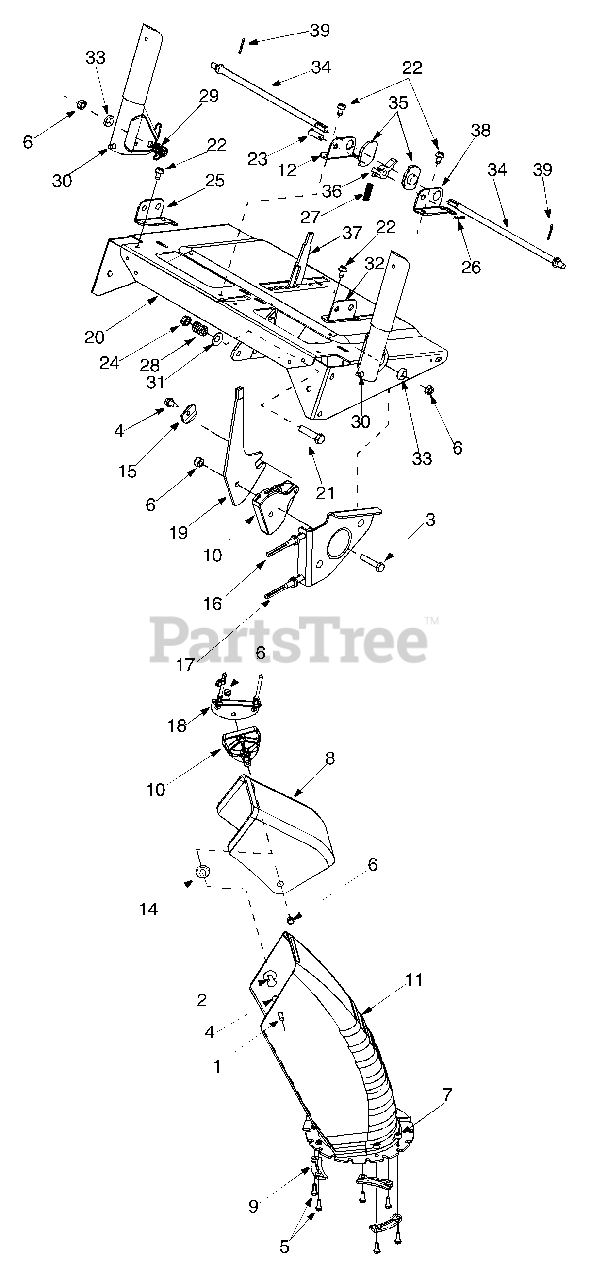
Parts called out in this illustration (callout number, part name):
1	Carriage Screw
2	Carriage Bolt 5/16-18 x 1.75"
3	Hex Bolt 5/16-18 x 1.5"
4	Hex Screw 1/4-15 x.750"
5	Hex Screw 1/4-20 x 1.00"
6	Flange Lock Nut, 5/16-18
7	Flange Lock Nut, 1/4-20
8	Upper Chute
9	Chute Flange Keeper
10	Chute Tilt Cable Guide
11	Lower Chute
14	Flat Washer
15	Special Washer
16	Chute Control Cable
17	Chute Cable w/Clip
21	Hex Bolt 3/8-24 x 1.5"
22	TT Screw 1/4-20 x 0.5"
23	Clevis Pin
26	Cotter Pin
29	Torsion Spring
30	Rubber Bumper
31	Bell Washer
33	Special Washer
35	Cam Handle Lock
36	Handle Lock Pawl
39	Cotter Pin
